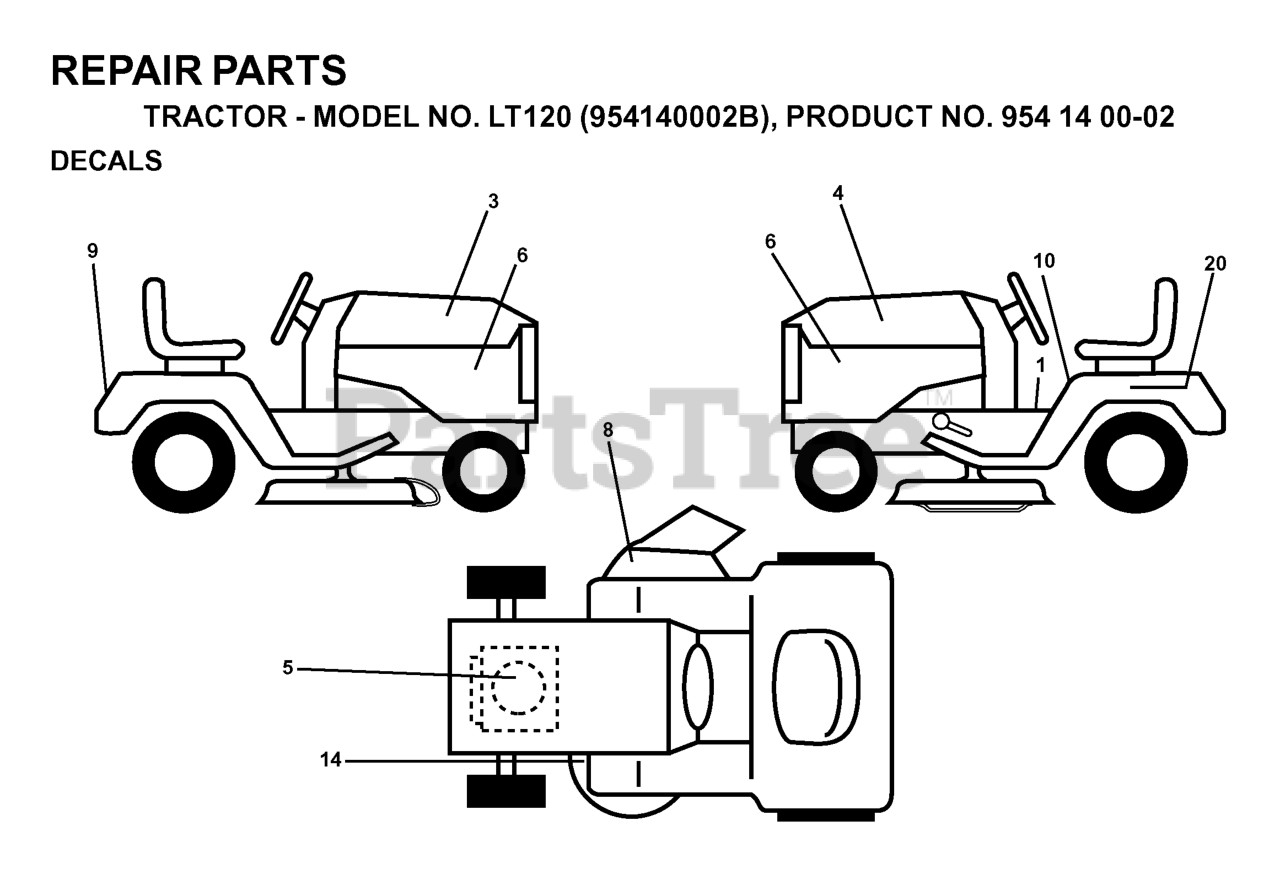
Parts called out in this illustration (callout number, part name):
1	DECAL FEND STLT OPER INST E/F
5	DECAL, ENGINE
6	DECAL PNL SIDE
8	DECAL WARNING (ENGLISH/FRENCH)
9	DECAL FENDER HUSQ
10	DECAL FENDER DANGER
14	DECAL V-BELT SCHEMATIC
20	DECAL BTRY SYMBOLS
